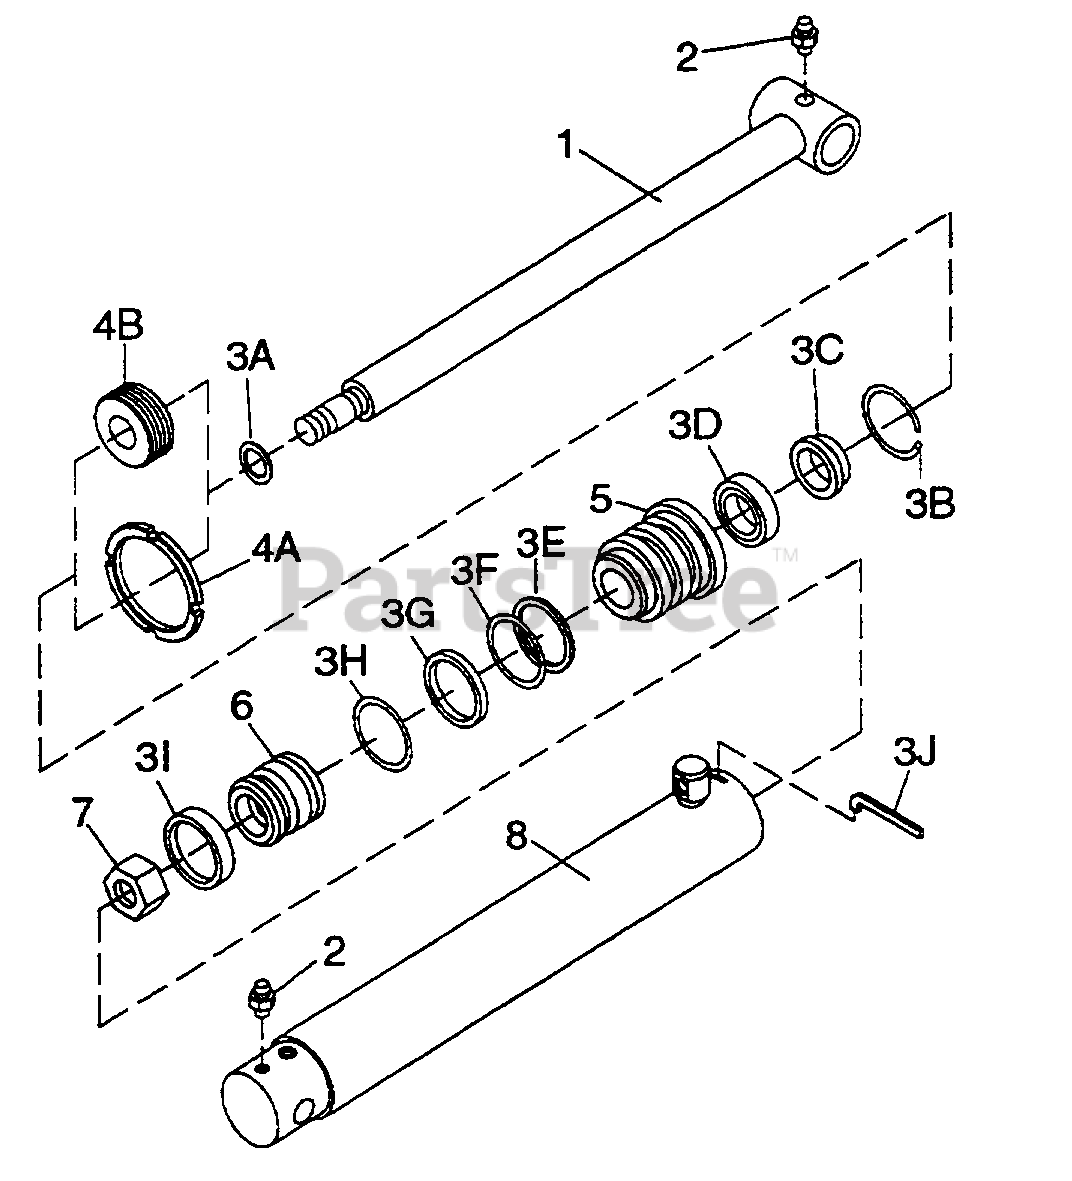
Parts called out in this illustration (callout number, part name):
1	Piston rod, 1-1/4 diameter
2	Grease fitting, 1/4-28 tapered thread
3A	O-Ring, 3/4 ID x 7/8 OD
3B	Round retaining ring, 2-1/2 internal
3D	U-Cup, 1-1/4 ID x 5/8 OD x 5/16 deep
3E	Back-up washer, 2-1/4 ID x 2-1/2 OD
3F	O-Ring, 2-1/4 ID x 2-1/2 OD
3G	Piston ring, Teflon 2-1/2 OD
3H	O-Ring, 2-1/16 ID x 2-1/4 OD
3I	Wear ring, 2-1/2 OD x 1/2 x 1/8 thick
3J	Retaining wire
4A	Spanner nut, .250 x 2.875 OD
4B	Threaded retainer, 2-1/2 diameter
5	Rod guide with thread 2-1/2 diameter
5	Rod guide, 2-1/2 diameter
6	Piston, 2-1/2 OD
7	7/8 NF Self-lock hex nut
8	Cylinder barrel, 2-1/2 OD
